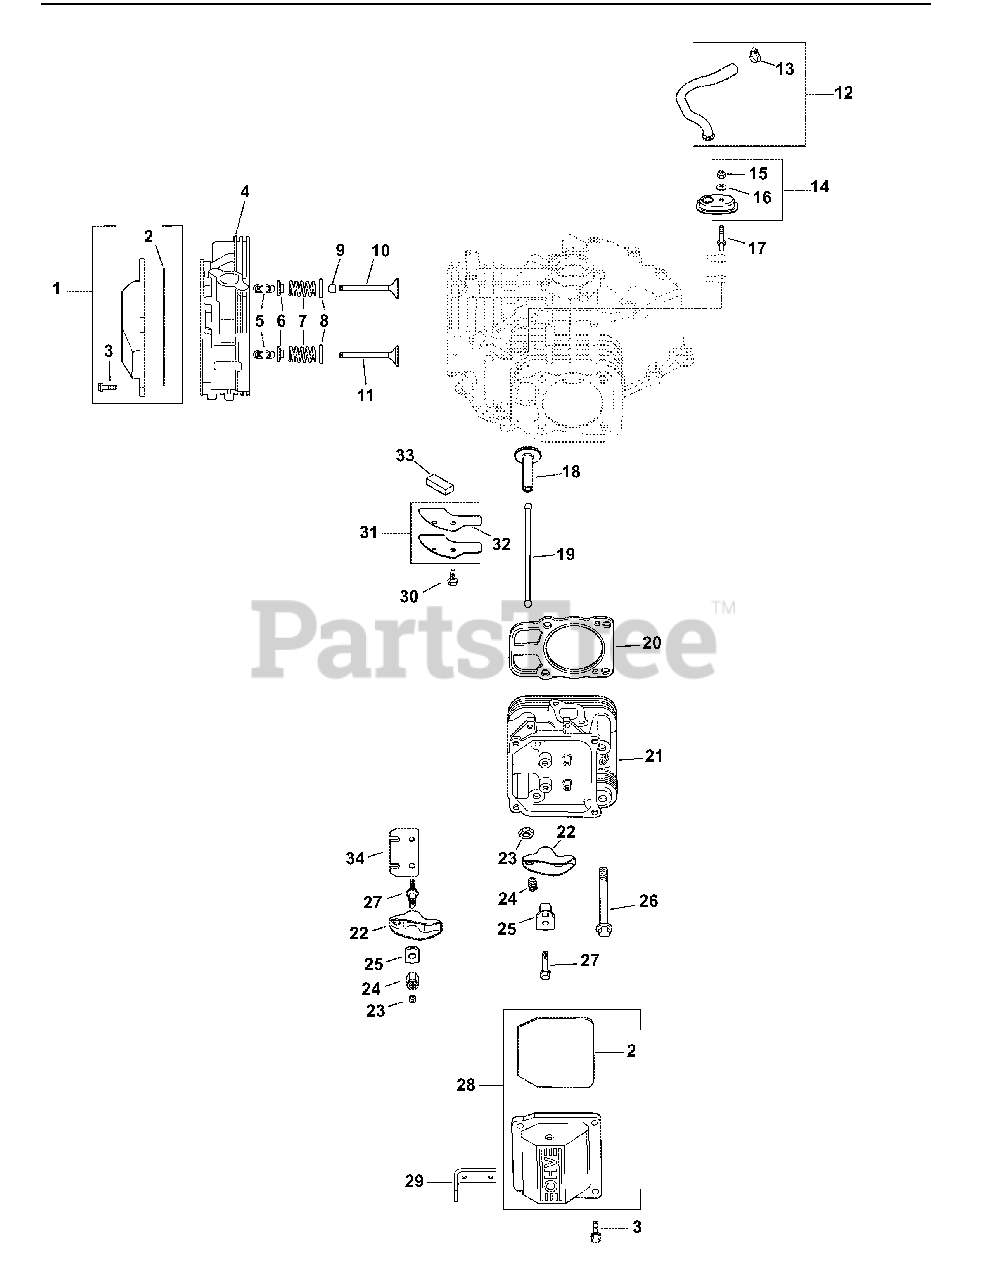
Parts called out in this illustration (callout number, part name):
1	KIT, PLAIN ROCKER COVER (INCLUDES 2(QTY 1), 3(QTY 4)
2	O-RING, VALVE COVER
3	SCREW, FLG M6X1.0X30
4	KIT, #1 CYLINDER HEAD ASSY
5	KIT, RETAINER
6	CAP, VALVE SPRING
7	SPRING, VALVE
8	RETAINER, SPRING
9	SEAL, VALVE STEM
10	VALVE, INTAKE (STD)
11	VALVE, EXHAUST (STD)
12	KIT, BREATHER HOSE (INCLUDES 13(QTY 1)
13	CLAMP, HOSE
14	KIT, BREATHER HOUSING (INCLUDES 15,16)
15	NUT, LOCK M5X0.8
16	WASHER, SEALING
17	STUD, BREATHER COVER
18	KIT,TAPPET
20	KIT, CYLINDER HEAD GASKET
21	KIT, #2 CYLINDER HEAD ASSY
23	NUT, M10X0.75
24	SCREW, SET
25	PIVOT, ROCKER ARM
26	SCREW, FLG M10X1.5X90
28	KIT, BREATHER VALVE COVER (INCLUDES 2 (QTY 1)
29	STRAP, LIFTING
30	SCREW, FLG THD FRM M6X1.0X16
31	KIT, BREATHER COVER (INCLUDES 32)
32	GASKET, BREATHER COVER
33	FILTER, BREATHER
